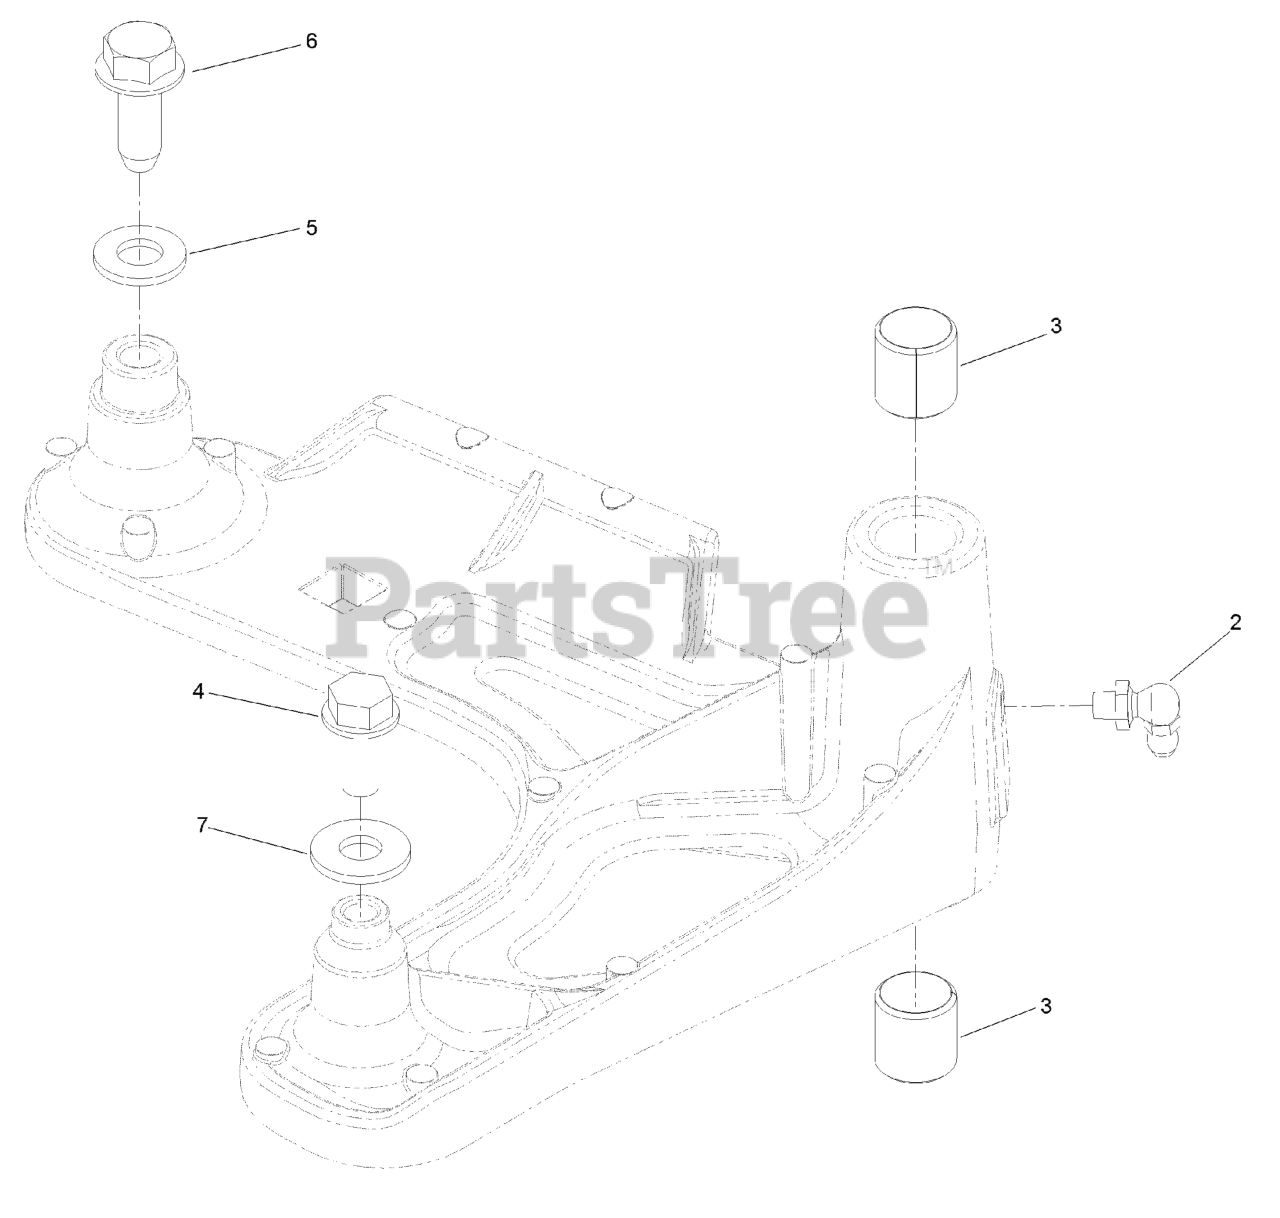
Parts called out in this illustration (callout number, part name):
2	FITTING-GREASE, 90 DEG
3	SLEEVE-BEARING
4	SCREW-THD ROLL, HWH
5	WASHER-FLAT
6	SCREW-FORMING, THREAD
7	WASHER-FLAT
